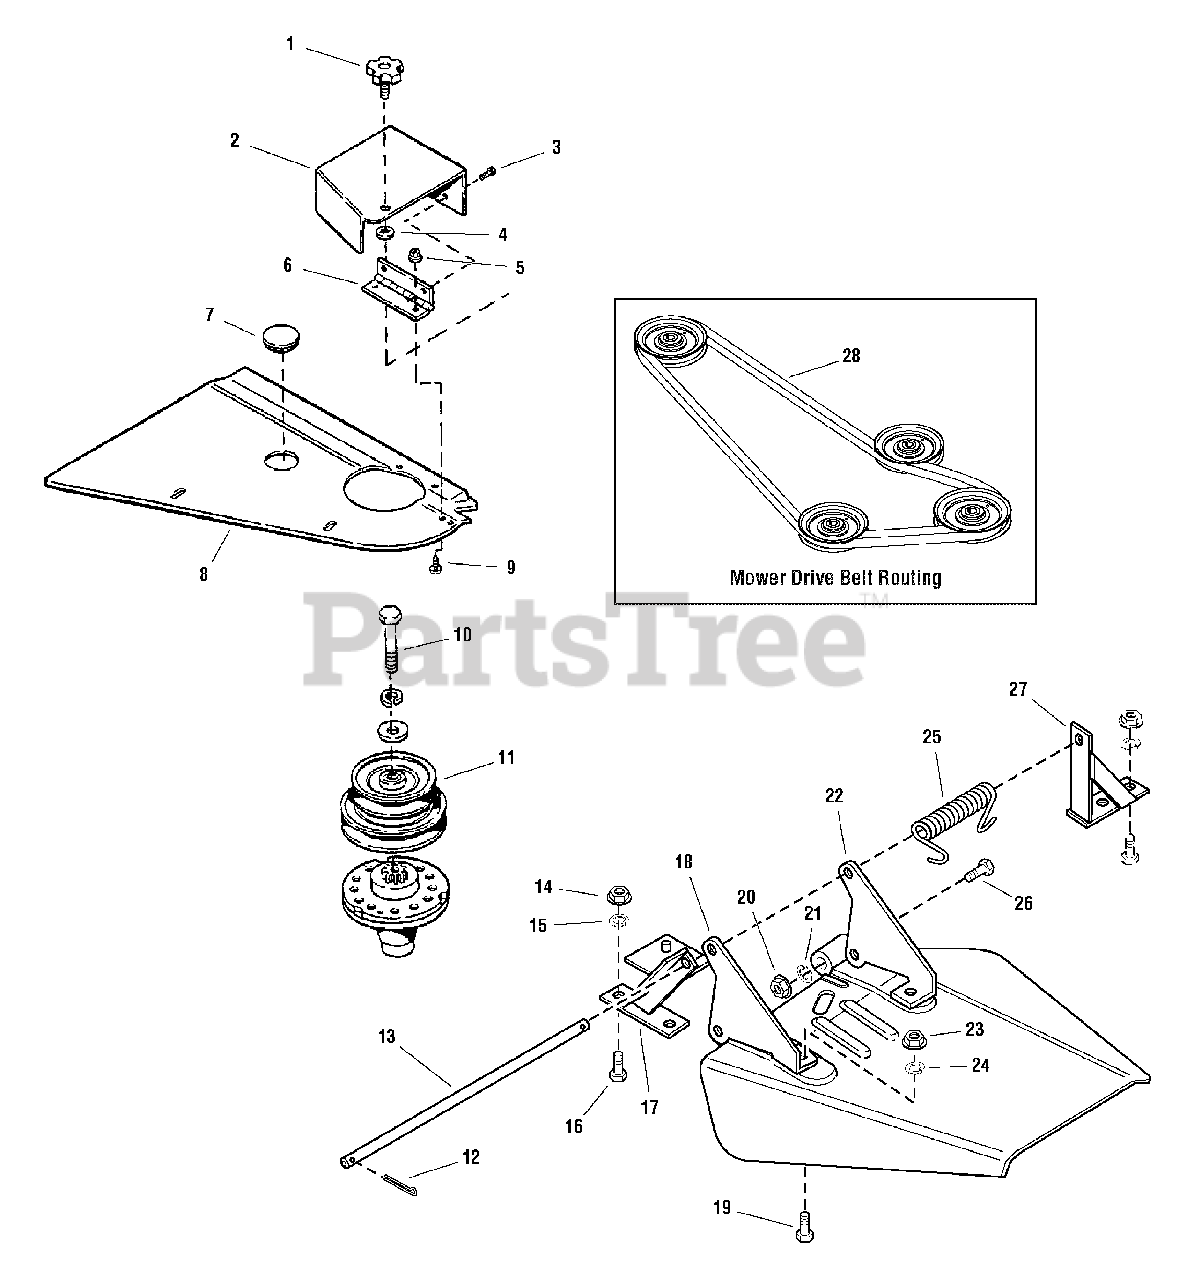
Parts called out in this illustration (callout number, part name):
1	KNOB, Plastic
2	COVER, Belt
3	POP-RIVET, 3/16 x 5/16
4	NUT, Push, 5/16
5	NUT, Hex Flange, #10-32
6	HINGE
7	PLUG, Mower Cover
8	COVER, LH Mower
9	SCREW, Machine, #10-32 x 3/8
10	CAPSCREW, Hex Head, 7/16-14 x 2-1/4
11	PULLEY ASSEMBLY
12	PIN, Cotter
13	ROD, Pivot
14	NUT, Hex, 3/8-16
15	WASHER, Lock, 3/8
16	CAPSCREW, Hex Head, 3/8-16 x 1
17	HINGE ASSEMBLY, Front
18	BRACKET, L.H. Pivot
19	CAPSCREW, Hex Head, 5/16-18 x 7/8
20	NUT, Hex, 7/16-14
21	WASHER, Lock, 7/16
22	BRACKET, R.H. Pivot
23	NUT, Hex, 5/16-18
24	WASHER, Lock, 5/16
25	SPRING, Torsion
26	CAPSCREW, Hex Hd, 7/16-14 x 2-3/4
27	HINGE ASSEMBLY, Rear
28	V-BELT, Cog, 48.7 Lg
